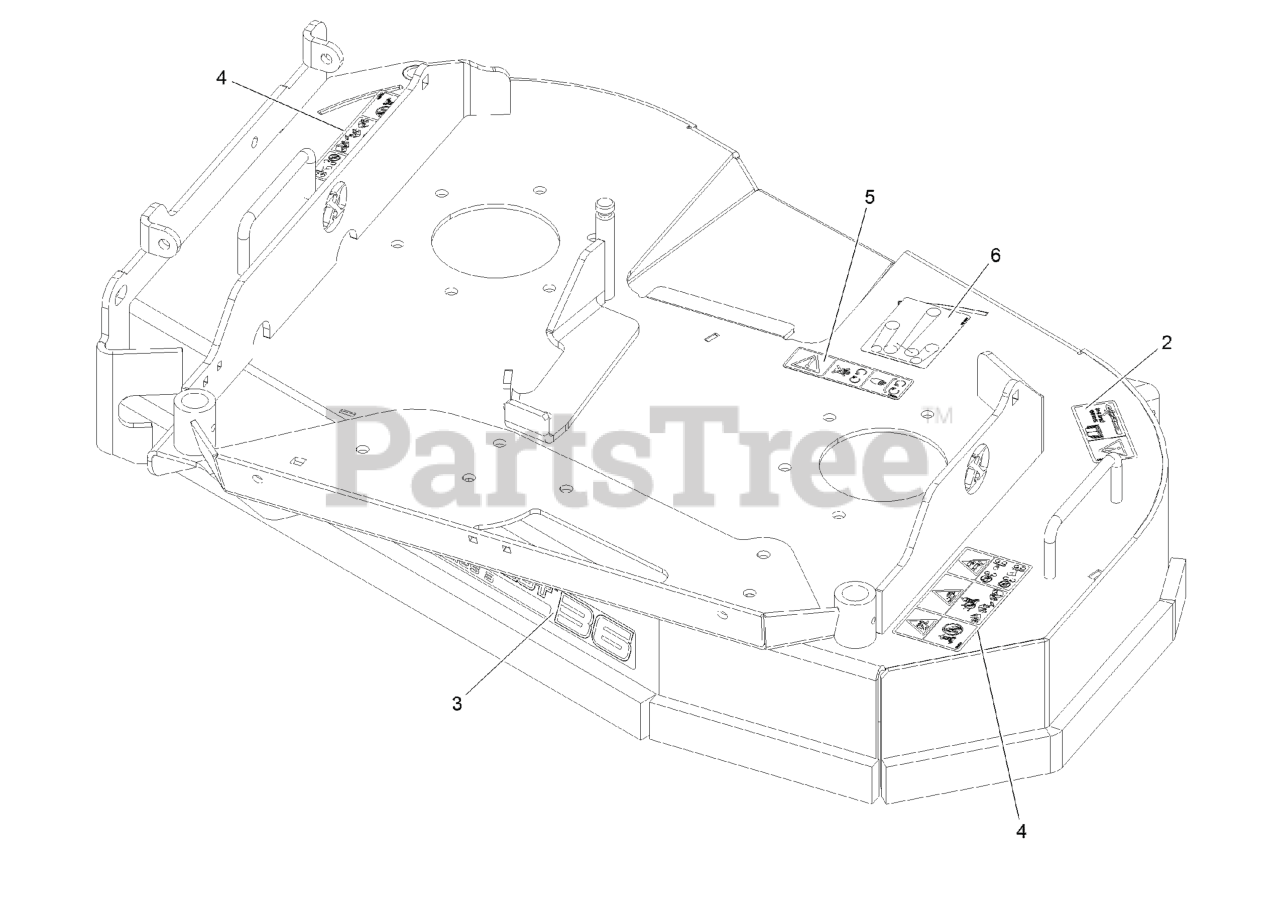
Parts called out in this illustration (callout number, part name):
2	DECAL-TORQUE, BOLT
3	DECAL-ULTRACUT 36 SERIES 3
4	DECAL-WARNING THROWN OBJ
5	DECAL-COVER, MISSING
6	DECAL-BELT ROUTING
